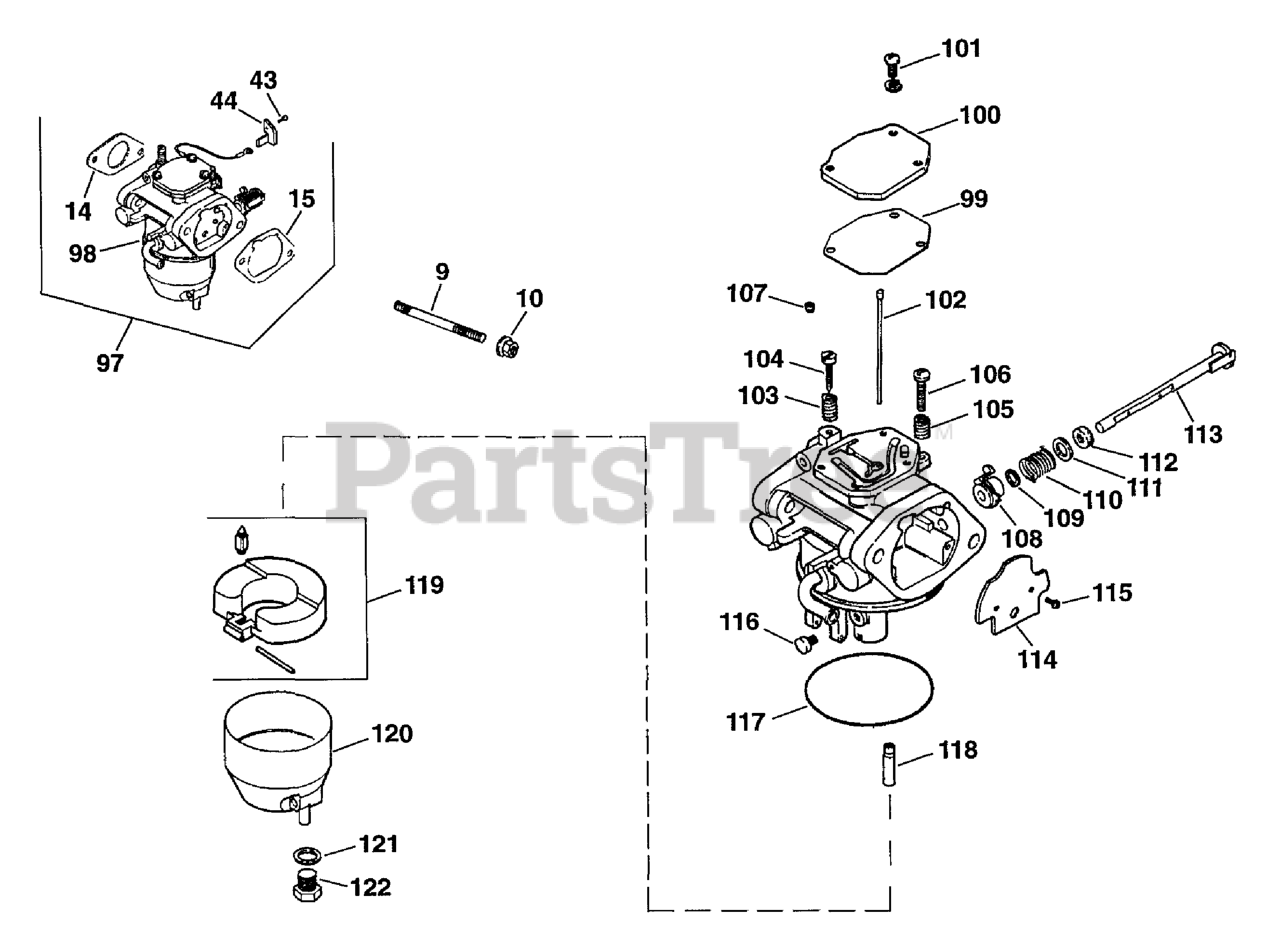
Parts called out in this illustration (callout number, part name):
9	Stud, M6x1.0x95
10	NUT - USE M-641060
14	GASKET, CARBURETOR
15	GASKET, AIR CLEANER BASE
43	BRACKET, THROTTLE STOP
44	Screw, phillips hd. M2x0.45x6
